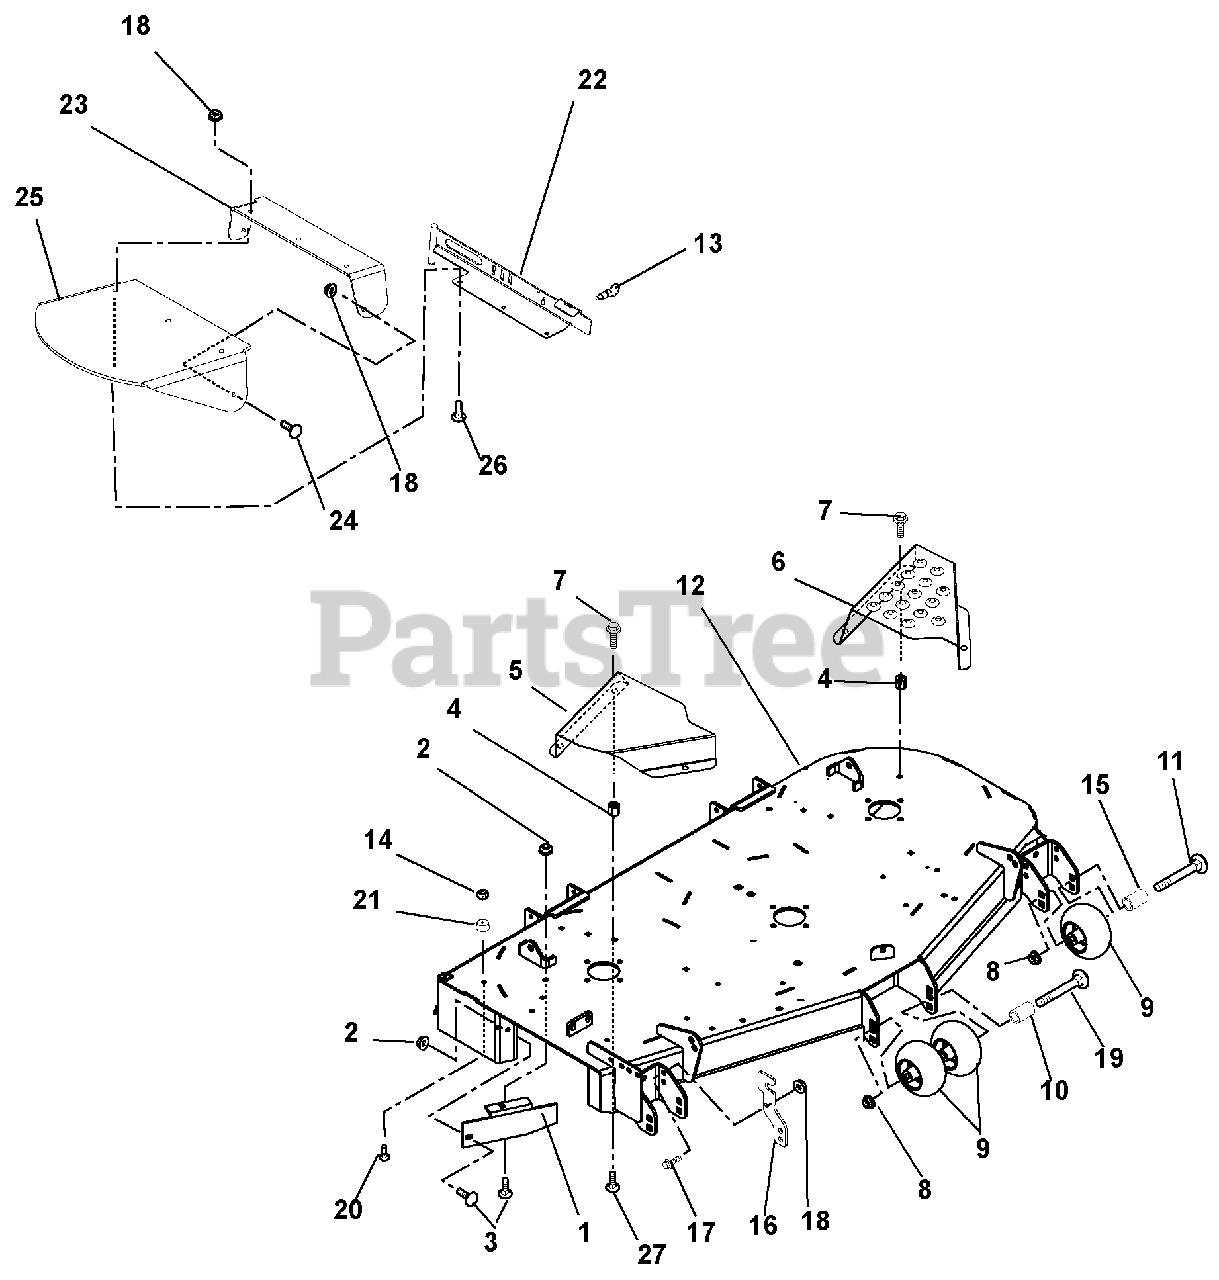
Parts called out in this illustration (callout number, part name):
1	52-in. Discharge Baffle (992212)
2	Nut, .31-18 Nyloc Flange
3	Bolt, Round Head Square Neck .31-18 x 1.00 Grade 5
4	Nut, Heavy Hex .38-16
5	52-in. Right Hand Spindle Guard (992212)
6	52-in. Left Hand Spindle Guard (992212)
7	Nut, Spin Lock Flange .375-16
8	Nut .50-13 Nyloc Flange
9	Anti-Scalp Wheel
11	Bolt, Round Head Square Neck .50-13 x 5.00
12	52-in. Pro-Master 200 Side Discharge Deck Weldment (992212)
13	Pin, Plunger Pull .50-13 Thread x .310 Diameter
14	Nut, Locking Center .31-18
15	Spacer, .510 x .625 x 3.35
16	Chute, Storage Bracket
17	Bolt, Hex .38-16 x 1.00 Grade 5
18	Nut, .38-16 Nyloc Flange
19	Bolt, Round Head Square Neck .50-13 x 8.50
20	Bolt, Round Head Square Neck .31-18 x 1.50
21	Bumper, Recessed 1.50 x .63 , .31 Thru Hole
22	Weldment, 52-inch and 60-inch Discharge Chute Mounting (992210, 212, 217)
23	Rubber Discharge Chute Support
24	Bolt, Round Head Square Neck .38-16 x 1.00 Grade 5
25	Chute, Rubber Discharge
26	Bolt, Round Head Square Neck .38-16 x 1.25 Grade 5
27	Bolt, Hex .38-16 x 1.25 Grade 5
